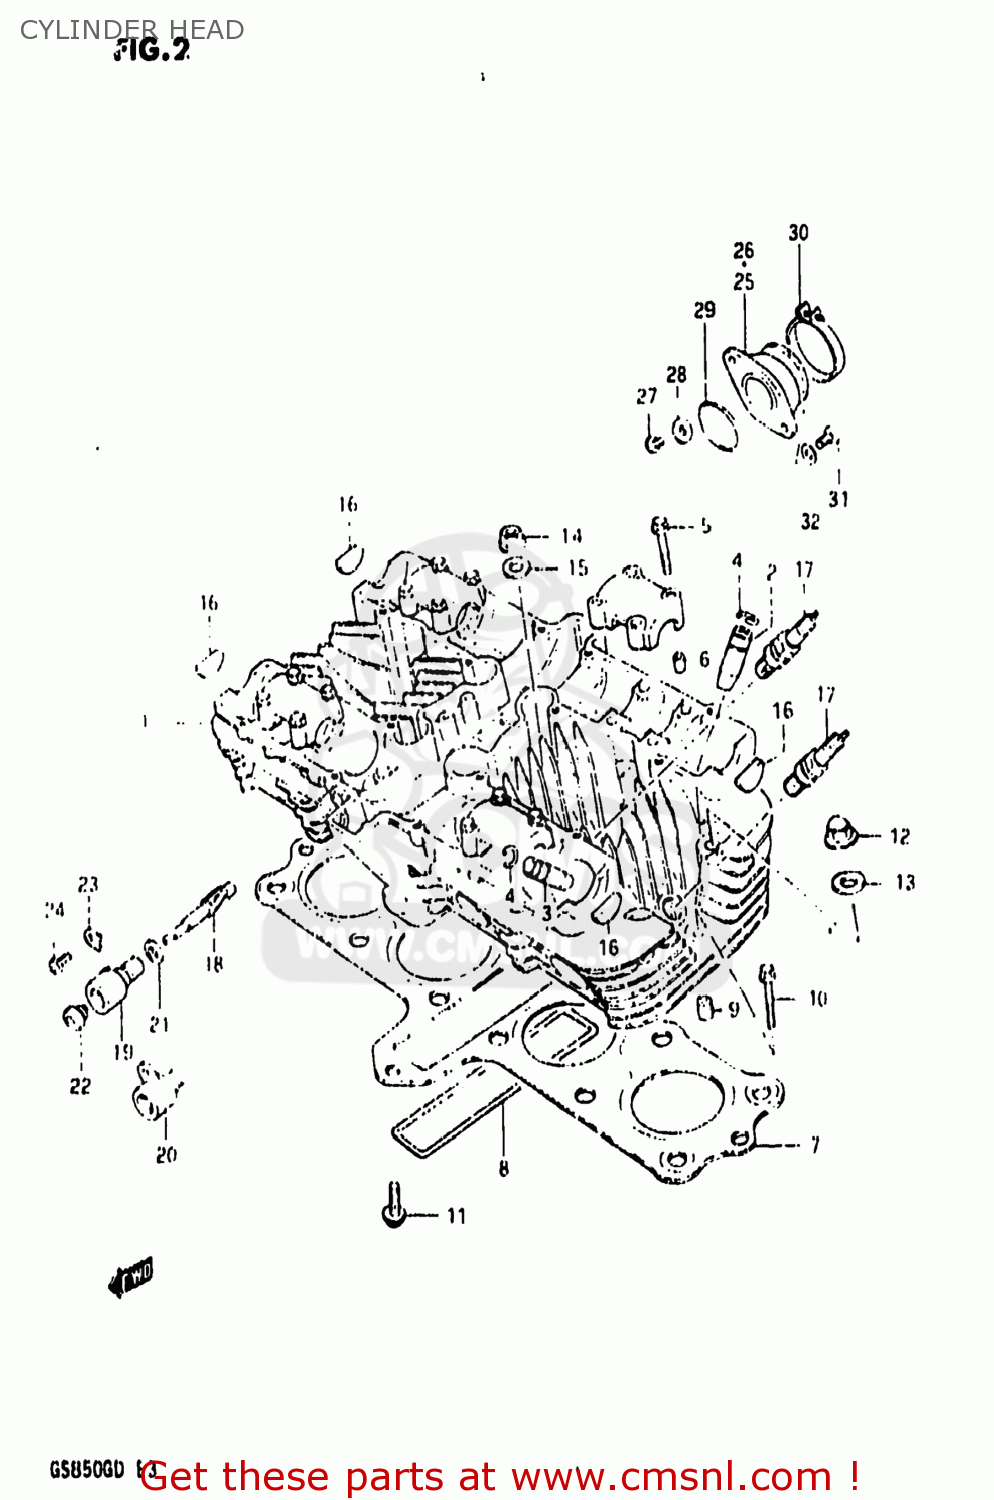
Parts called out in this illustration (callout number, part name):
1	HEAD ASSEMBLY,CYLINDER
2	GUIDE,INTAKE VALVE
3	GUIDE,EXHAUST VALVE
4	RING,SNAP
5	BOLT(6X39)
6	PIN(6.2X8X11)
7	GASKET,CYLINDER HEAD (MCA)
8	O RING(D:3,ID:26X157)
9	PIN
10	BOLT,UNDER
11	BOLT
12	NUT
13	GASKET(10.5X22X2) (NAS)
14	NUT
15	WASHER(10.5X22X2.3)
16	PLUG
17	SPARK PLUG
18	GEAR,TACHOMETER DRIVEN
19	SLEEVE,TACHOMETER DRIVE
20	SLEEVE,TACHOMETER DRIVE GEAR
21	SEAL,TACHOMETER DRIVEN
22	SEAL,OIL(5X12X8)
23	PLATE,TACH DRIVE GEAR SLEEVE
24	SCREW(5X12)
25	PIPE,INTAKE,R
26	PIPE,INTAKE,L
27	BOLT
28	GASKET(5.3X9.3X1.2) (NAS)
29	O-RING
30	CLAMP
31	SCREW
32	WASHER
